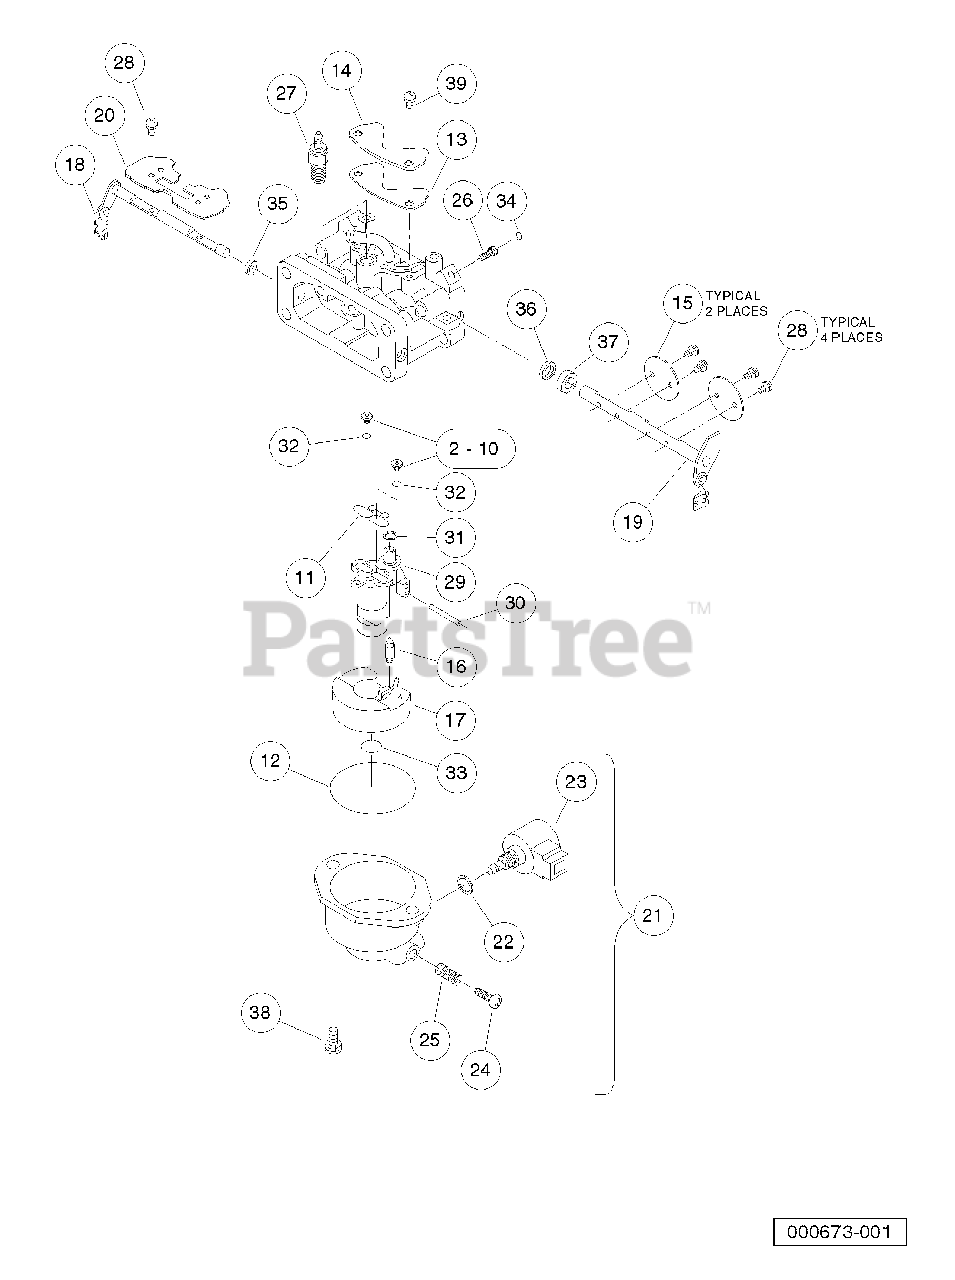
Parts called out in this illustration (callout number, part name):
1	Asm, Carburetor, Fh680d
2	Kit, Jet, 6600 Ft +, Fh680
4	Kit, Instructions Jet, Push In
5	Kit, Jet, 3300-6600 Ft, Fh680d
7	Kit, Instructions Jet, Push In
8	Kit, Jet, 0-3300 Ft, Fh680d
10	Kit, Instructions Jet, Push In
11	Gasket, FH680D
12	Gasket, Carburetor, Dia. 52
13	Gasket, Cover, FH680D
14	Cover, Slow Passage, FH680D
15	Valve, Throttle, FH680D
16	Valve, Float, FH680D
17	Float, Carburetor, FH680D
18	Shaft, Carburetor, FH680D
19	Shaft, Carburetor, Throttle
20	Valve, Carburetor, FH680D
21	Asm, Chamber, Float, Fh680d
22	Gasket, Carburetor, FH680D
23	Solenoid, Carburetor, FH680D
24	Screw, Drain, Carburetor
25	Spring, Carburetor, FH680D
26	Needle, Jet, FH680D
27	Heater, Carburetor, FH680D
28	Screw, Carburetor, M3 X 6
29	Spacer, Carburetor, FH680D
30	Pin, Carburetor, FH680D
31	O-Ring, Carburetor, Dia. 6.5
32	O-Ring, Carburetor, FH680D
33	O-Ring, Carburetor, Dia. 9
34	Plug, Expansion, Carburetor
35	Seal, Carburetor, Dia. 5.9
36	Seal, Carburetor, FH680D
37	Collar, Carburetor, FH680D
38	Screw, Carburetor, M5
39	Screw, Carburetor, M4
